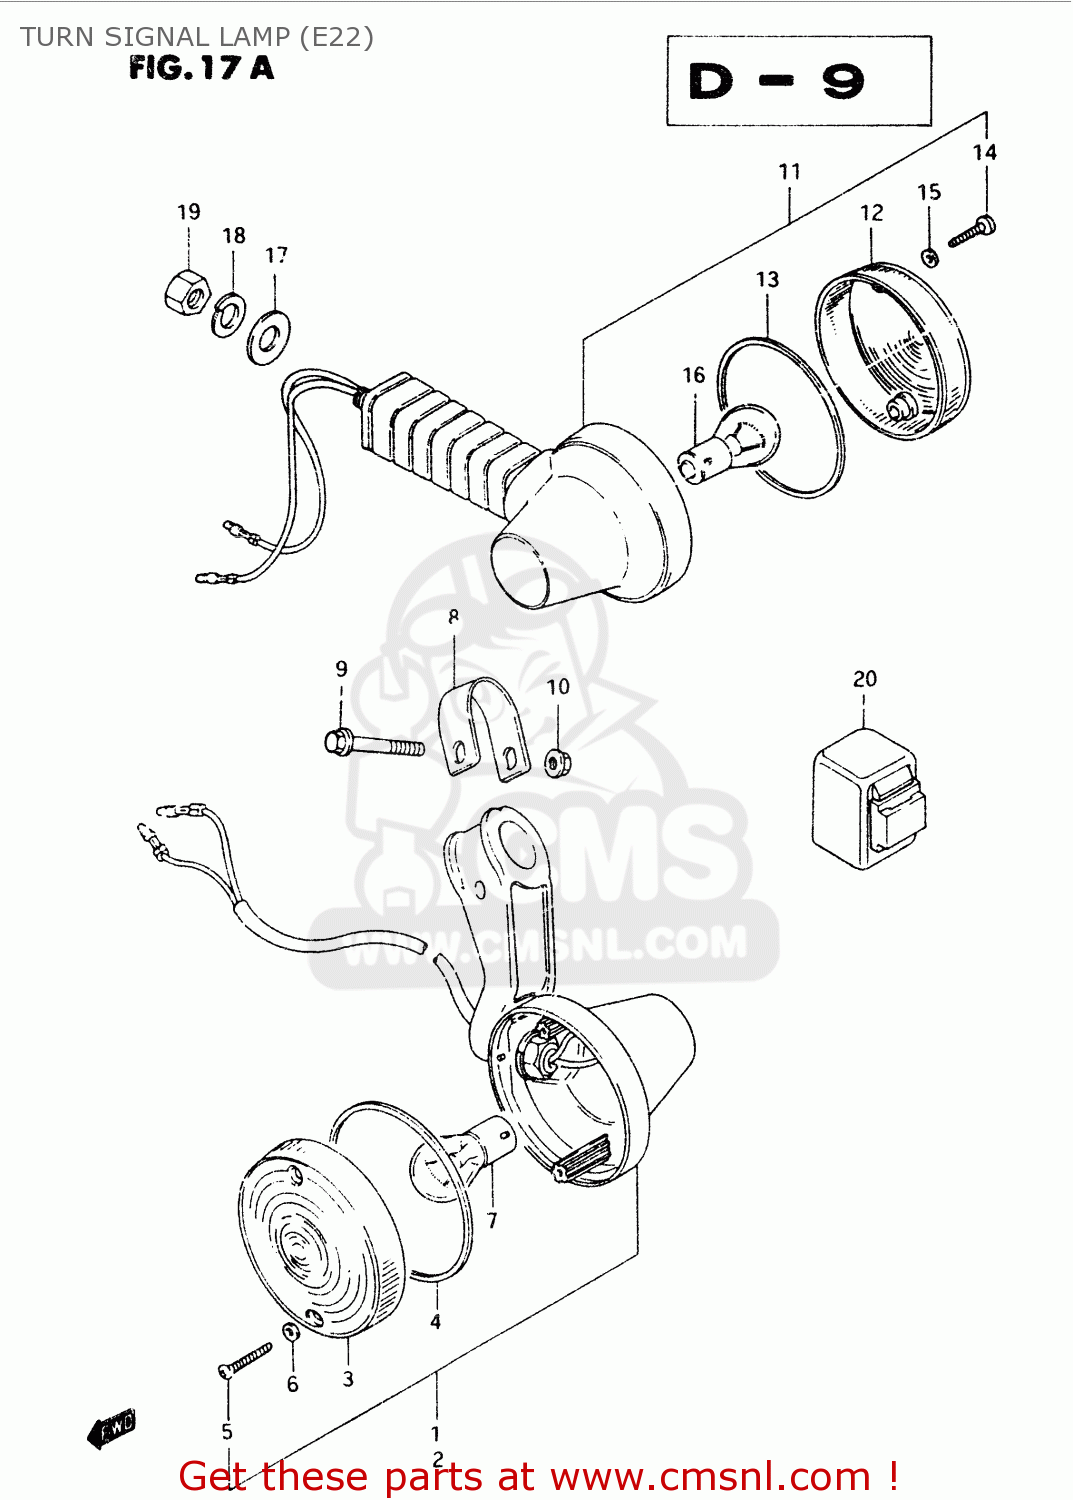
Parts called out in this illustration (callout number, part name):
1	LAMP, FRONT TURN SIGNAL RH
2	LAMP ASSY,FR TURN SIGNAL,L
3	LENS
4	GASKET (NAS)
5	SCREW
6	GASKET (NAS)
7	BULB(12V21W)
8	PLATE
9	BOLT 5X42
10	NUT
11	LAMP ASSY,FRONT TURNSIGNAL
12	LENS
13	GASKET (NAS)
14	SCREW
15	GASKET (NAS)
16	BULB(12V21W)
17	WASHER (12.5X26X1.6)
18	WASHER
19	NUT
20	RELAY ASSY,TUR
